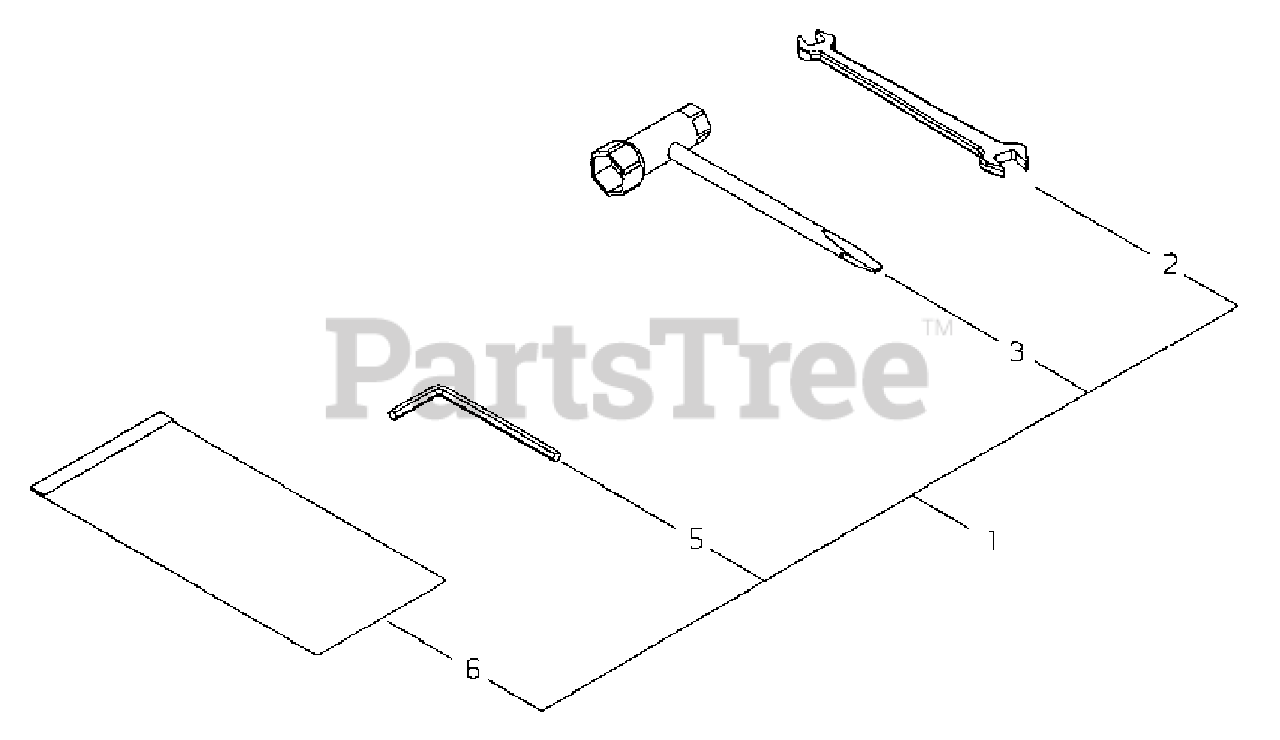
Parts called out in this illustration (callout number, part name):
1	TOOL KIT, SERVICE
2	SPANNER 8×10
3	T-WRENCH 16×13
5	WRENCH, ALLEN 4 MM
6	BAG, TOOL
